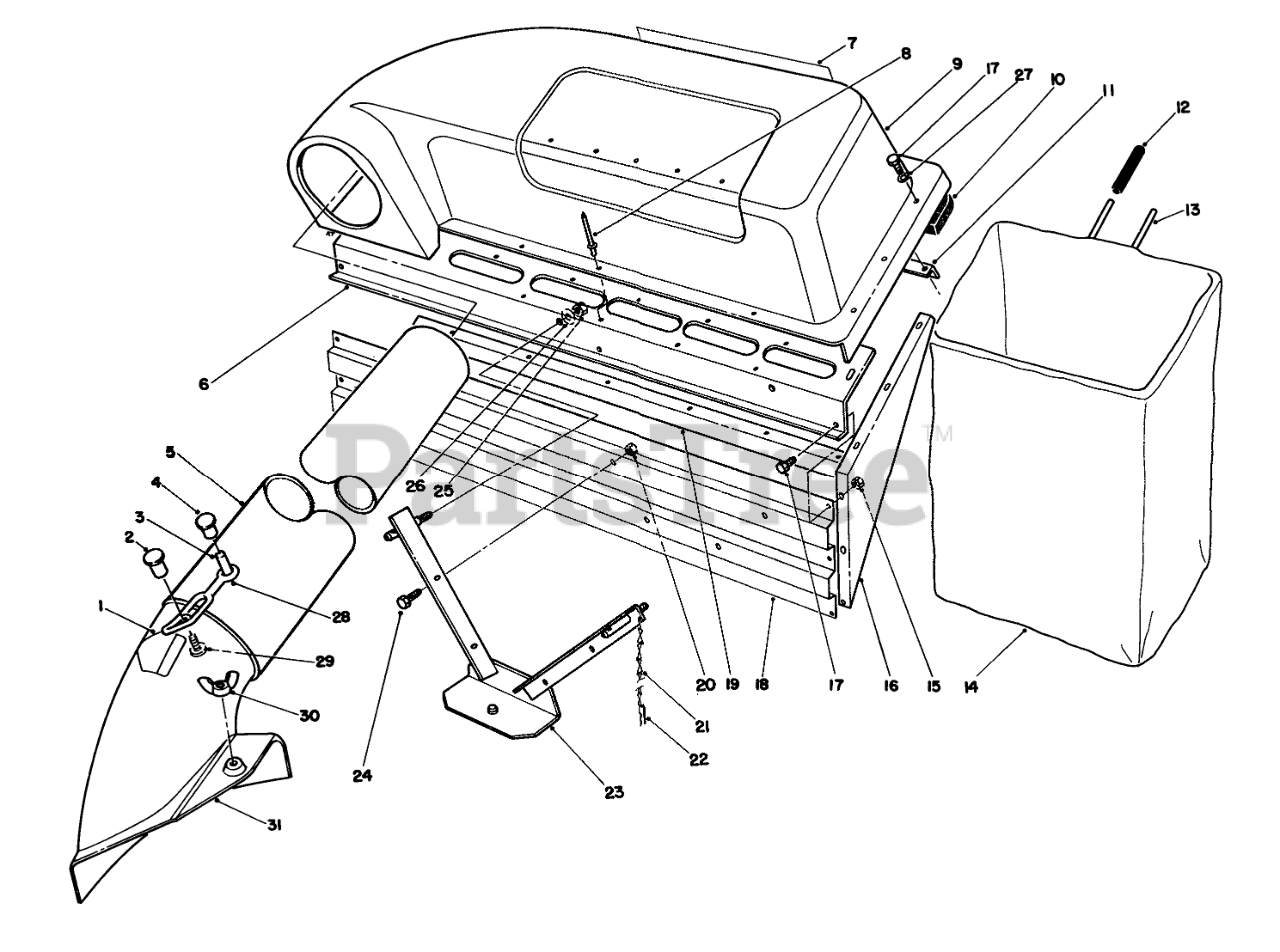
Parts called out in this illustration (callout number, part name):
1	DECAL-DANGER
3	SPACER-INTERLOCK
4	Fastner-Panel
6	COVER SUPT BAFFLE B
7	Decal-Twin Bagger
8	RIVET-POP
9	COVER
10	FOAM SEAL
11	BAG FRAME BRKT
12	GRIP-HANDLE, BAG
13	BAG FRAME
15	NUT-LOCK, NI
16	Plate-Side
17	SCREW-HH
18	COVER
19	BAG SUPPORT CHANNEL
20	NUT-LOCK, NI
21	6-LINK CHAIN W/HOOK
22	PIN-HAIR
23	V-Bracket
24	SCREW-HH
25	NUT-LOCK, NI
26	WASHER-FLAT
27	WASHER-FLAT
28	RETAINER-DUCT
29	Screw
30	NUT-WING SPECL
31	Assembly-Chute (Incl. Ref. #1, 2 & 29)
